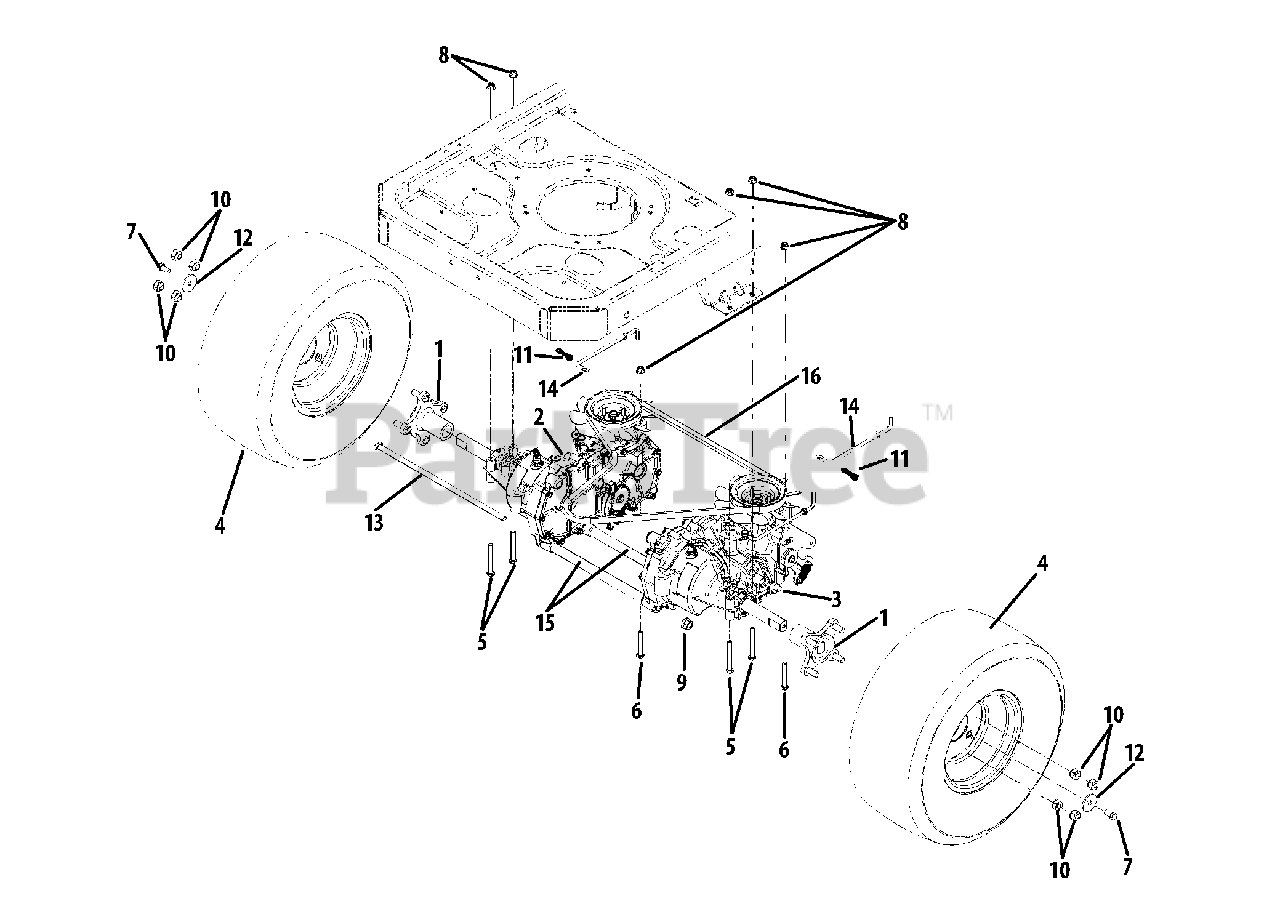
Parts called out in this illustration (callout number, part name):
1	Wheel Hub, 7/16-14 x 1.6
2	Transmission Assembly, LH
3	Transmission Assembly, RH
4	Wheel Assembly, 18 x 8.5-8
5	Hex Cap Screw, 5/16-18 x 2.75
6	Hex Cap Screw, 5/16-18 x 2.25
7	Hex Cap Screw, 3/8-16 x .75
8	Hex Flange Nut, 5/16-18
9	Hex Flange Nut, 7/16-20
10	Lug Nut, 7/16-14
11	Bow-Tie Cotter Pin
12	Flat Washer, .39 x 1.5 .134
13	Rod, .405 x 14.0
14	Bypass Rod
15	Tube, .45 x .69 x 10.2
